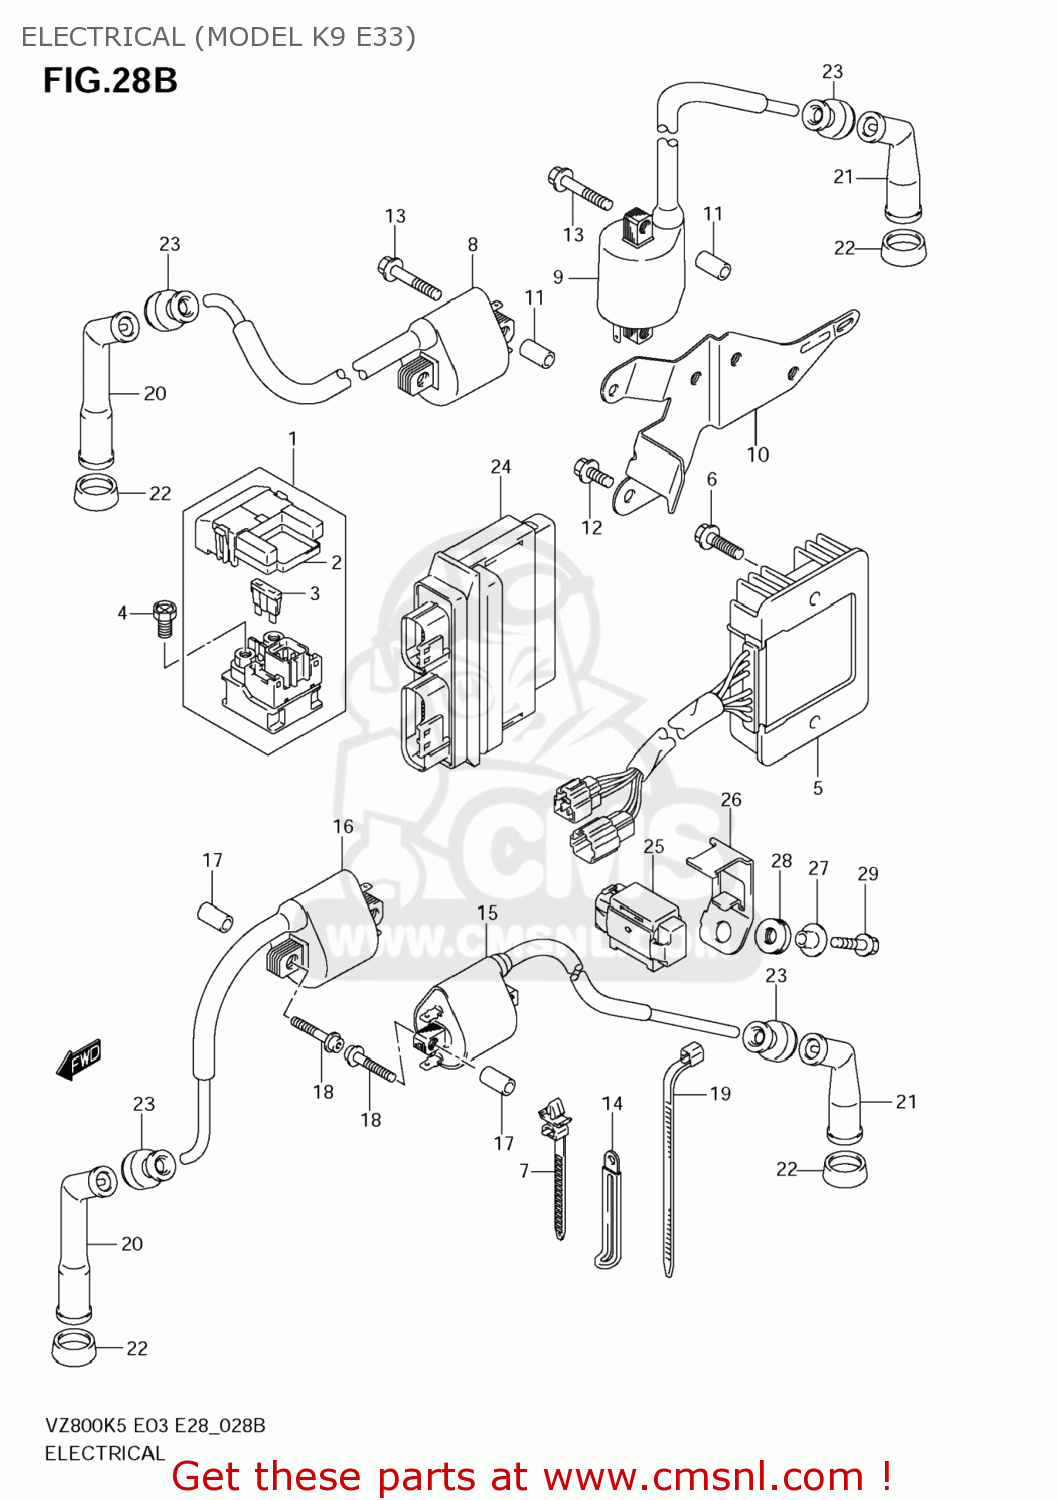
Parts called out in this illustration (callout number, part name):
1	RELAY ASSY,STARTING MOTOR
2	COVER
3	FUSE(30A)
4	SCREW(6X8)
5	RECTIFIER ASSY
6	SCREW
7	CLAMP(L:90)
8	COIL ASSY,IGNITION RR
9	COIL ASSY,IGNITION RR
10	BRACKET,IGNITION COIL RR
11	SPACER(6.4X10X18)
12	BOLT
13	BOLT
14	CLAMP(L:80)
15	COIL ASSY,IGNITION FR
16	COIL ASSY,IGNITION
17	SPACER(6.4X10X18)
18	BOLT(5X35)
19	CLAMP(L:190)
20	CAP,SPARK PLUG
21	CAP,SPARK PLUG
22	SEAL,SPARK PLUG
23	SEAL,HIGH TENSION CORD
24	CONTROL UNIT,FI
25	SENSOR ASSY,FUEL CUT
26	BRACKET,FUEL CUT SENSOR
27	SPACER(6.2X8.4X6.9)
28	CUSHION
29	BOLT
